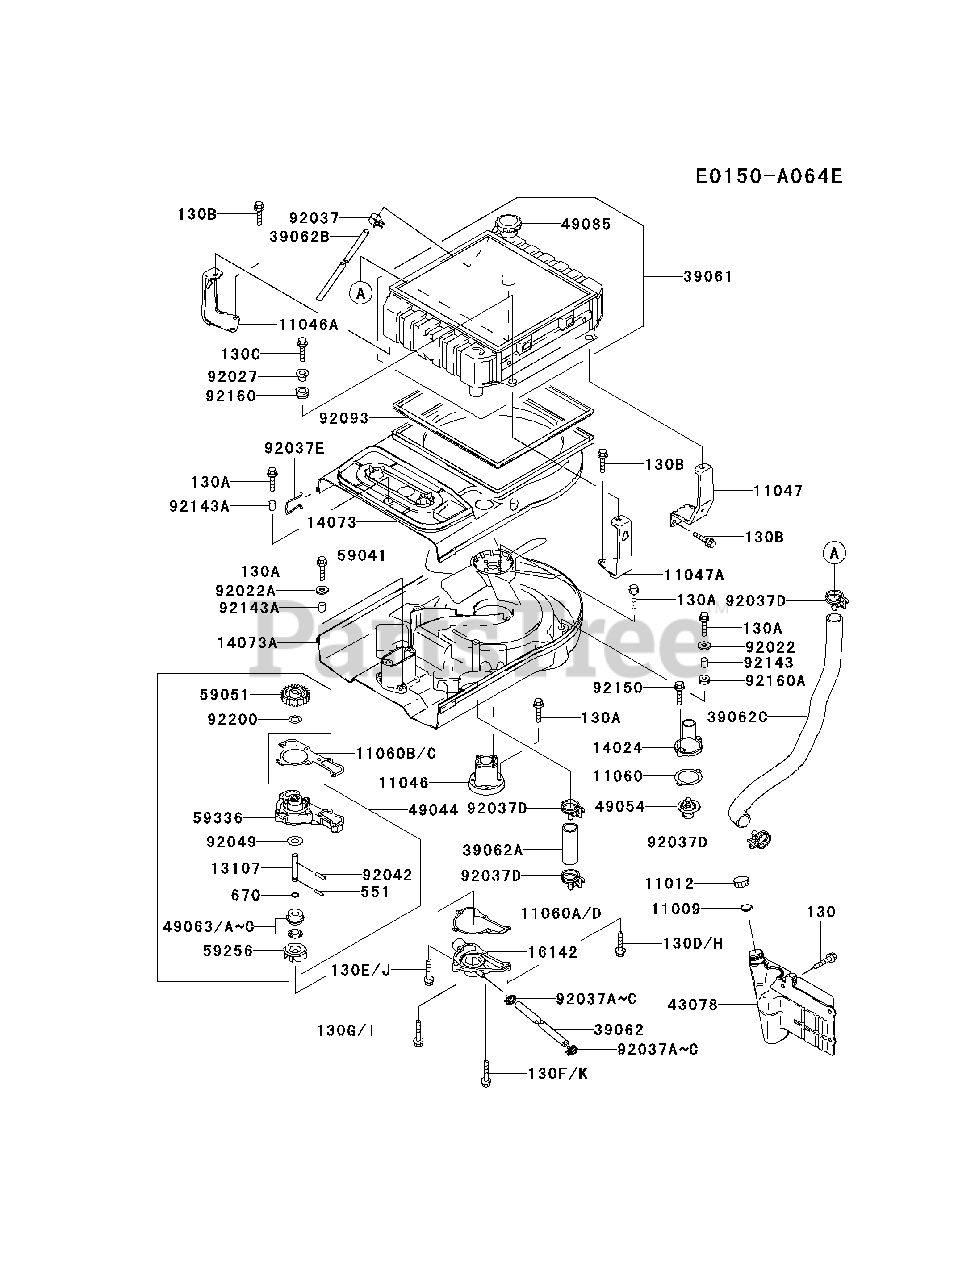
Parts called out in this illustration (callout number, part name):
130	BOLT-FLANGED
130A	BOLT-FLANGED
130B	BOLT-FLANGED
130C	BOLT-FLANGED
130H	BOLT-FLANGED
130I	BOLT-FLANGED
130J	BOLT-FLANGED
130K	BOLT-FLANGED
551	PIN-DOWEL
670	O RING
92150	BOLT,6X20
